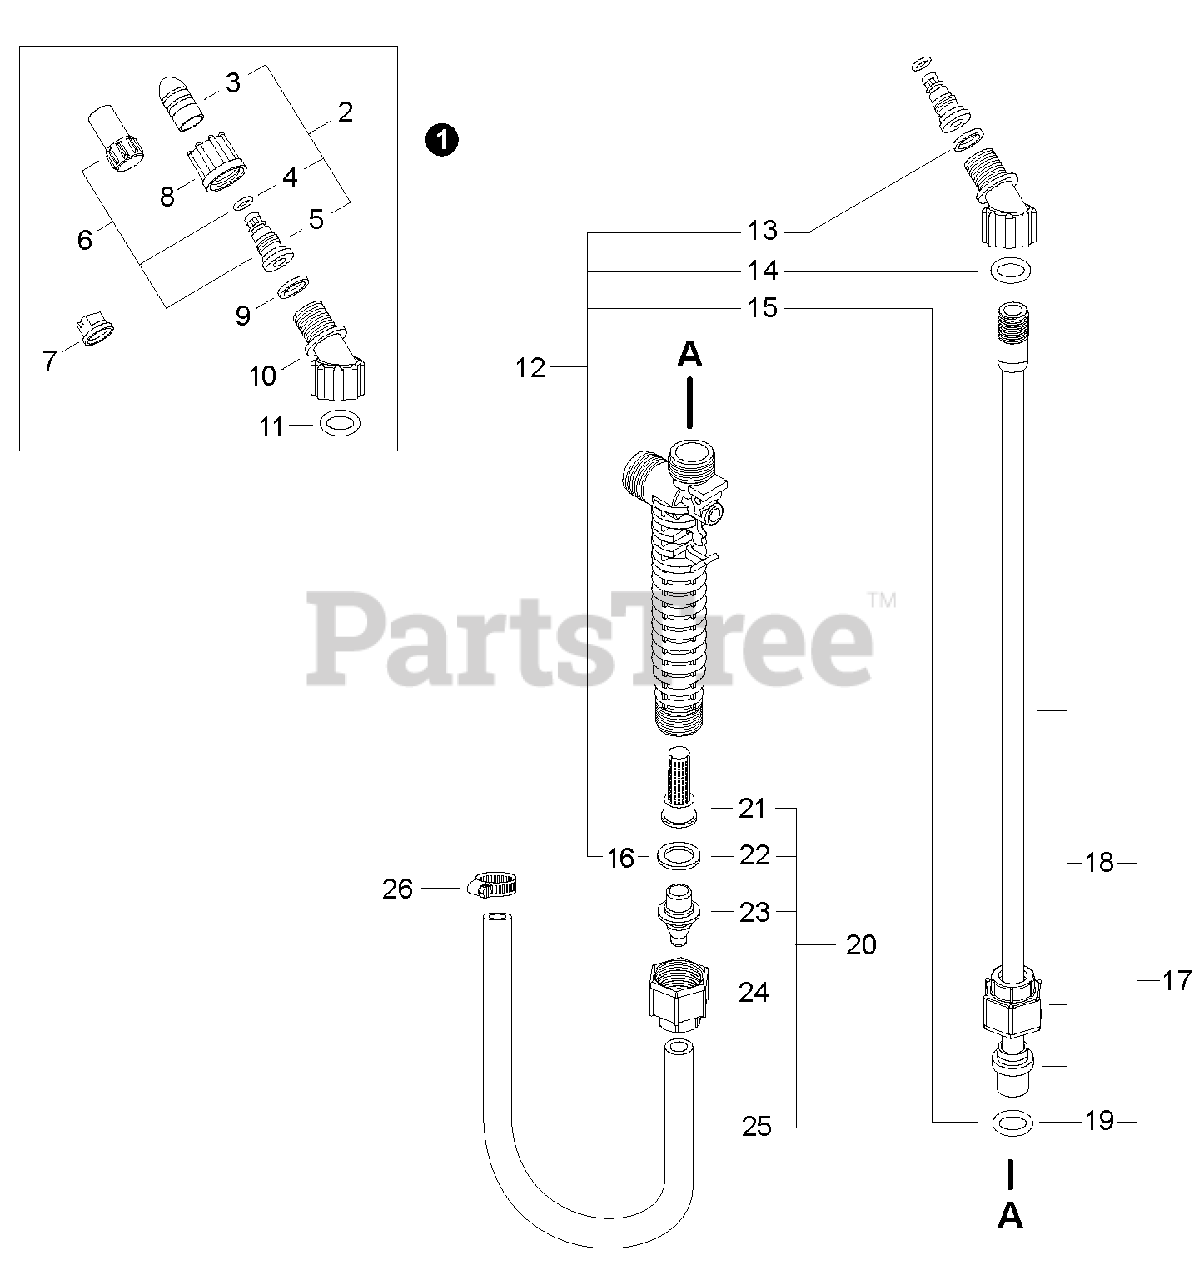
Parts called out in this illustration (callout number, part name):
1	NOZZLE KIT
2	NOZZLE KIT - BRASS
3	CAP, NOZZLE - BRASS
4	O-RING, NOZZLE
5	BODY, NOZZLE
6	NOZZLE KIT - PLASTIC
7	NOZZLE - FLAT FAN
8	NUT, NOZZLE
9	GASKET, NOZZLE
10	ELBOW, NOZZLE
11	O-RING, ELBOW
12	WAND GASKET KIT
13	GASKET, NOZZLE
14	O-RING, ELBOW
16	GASKET, ADAPTER
17	SPRAY WAND ASSY
18	WAND, SPRAYER
20	HOSE KIT
21	FILTER, SPRAY GUN
22	GASKET, ADAPTER
23	ADAPTER, HOSE - BLACK
24	NUT, HOSE
25	HOSE - 1210mm -- CLEAR
26	CLAMP, HOSE
